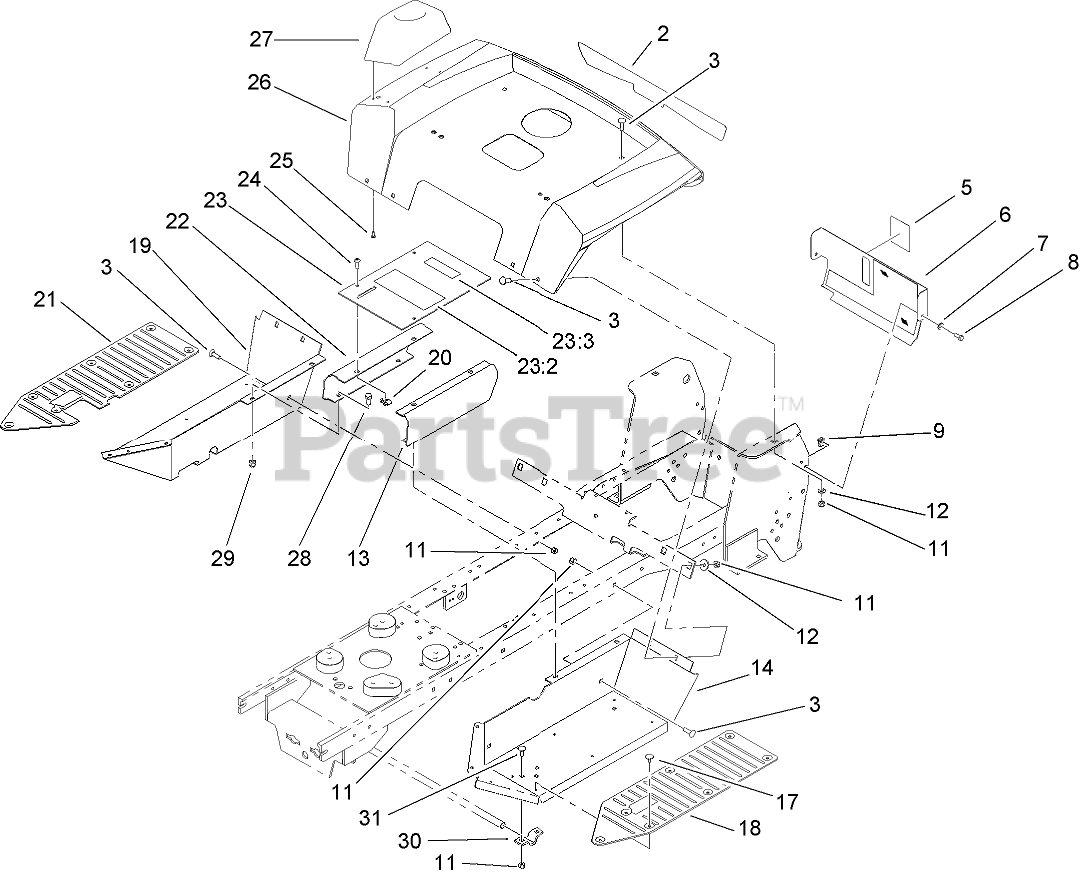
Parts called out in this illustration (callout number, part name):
2	DECAL-FENDER, REAR
3	SCREW-CARR
5	DECAL-LEVEL, FUEL
6	REAR PANEL ASM
7	WASHER-FLAT
8	SCREW-HH
9	NUT-SPEED
11	NUT-LOCK, NI
12	WASHER
13	CHANNEL-SADDLE, LH
14	FOOTREST-LH
17	FASTENER-PANEL
18	FOOTPAD-LH
19	FOOTREST-RH
21	FOOTPAD-RH
22	CHANNEL-SADDLE, RH
23	SADDLE PLATE DECAL ASM
23:2	DECAL-SLOPE/HYDRO
23:3	DECAL-MANUAL
24	SCREW-HH
25	SCREW-HHFTF
26	FENDER ASM
27	HOLDER-CUP
28	SCREW-HH
29	NUT-LOCK, NI
30	CLAMP
31	BOLT-CARR
